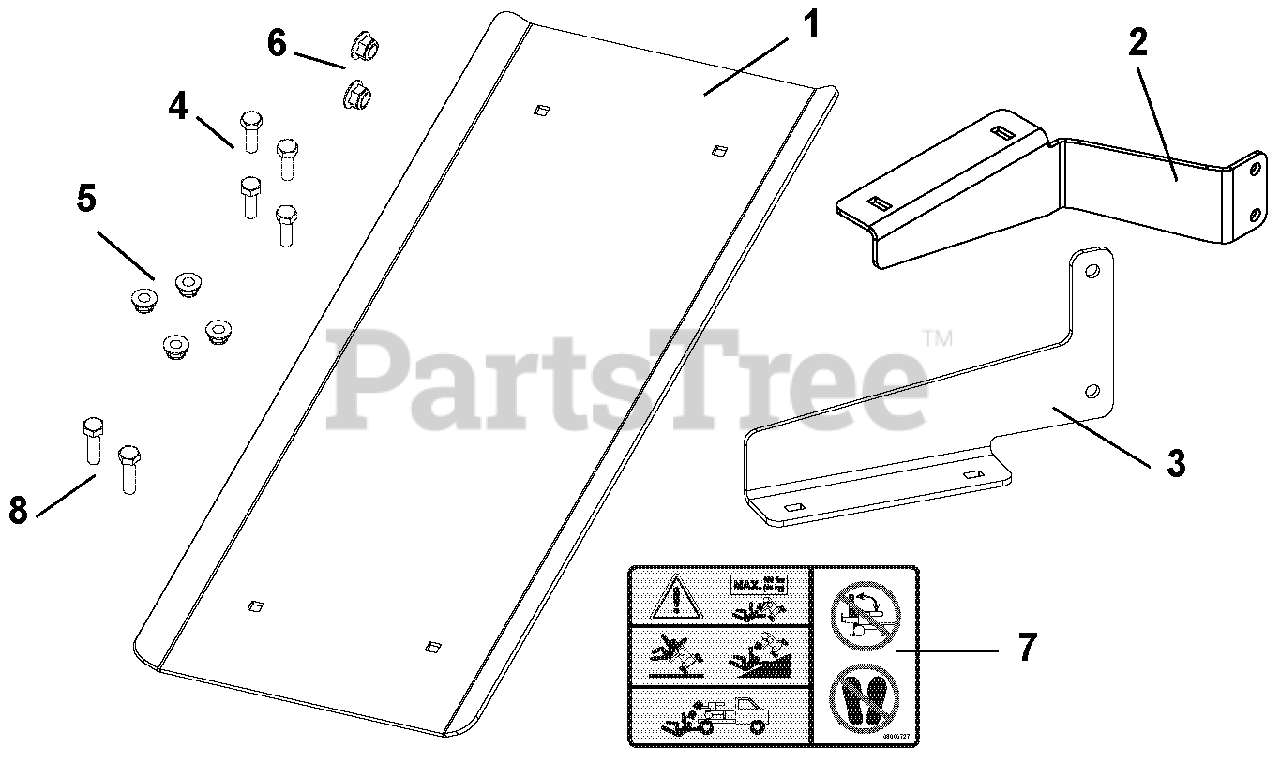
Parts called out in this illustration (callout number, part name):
1	TABLE, WORK - LOG SPLITTER
2	BRKT, REAR - WORK TABLE
3	BRKT, FRONT - WORK TABLE
4	@BLT-RHDSSQNK .31-18X1.00 G5YZ
5	@NUT-LK-NYL-FLG .31-18 YWZC
6	@NUT-LK-TOP-FLG .38-16 YWZC
7	DECAL,SPLITTER TABLE
8	@BLT-HEX .38-16X1.00 GR5 YWZC
